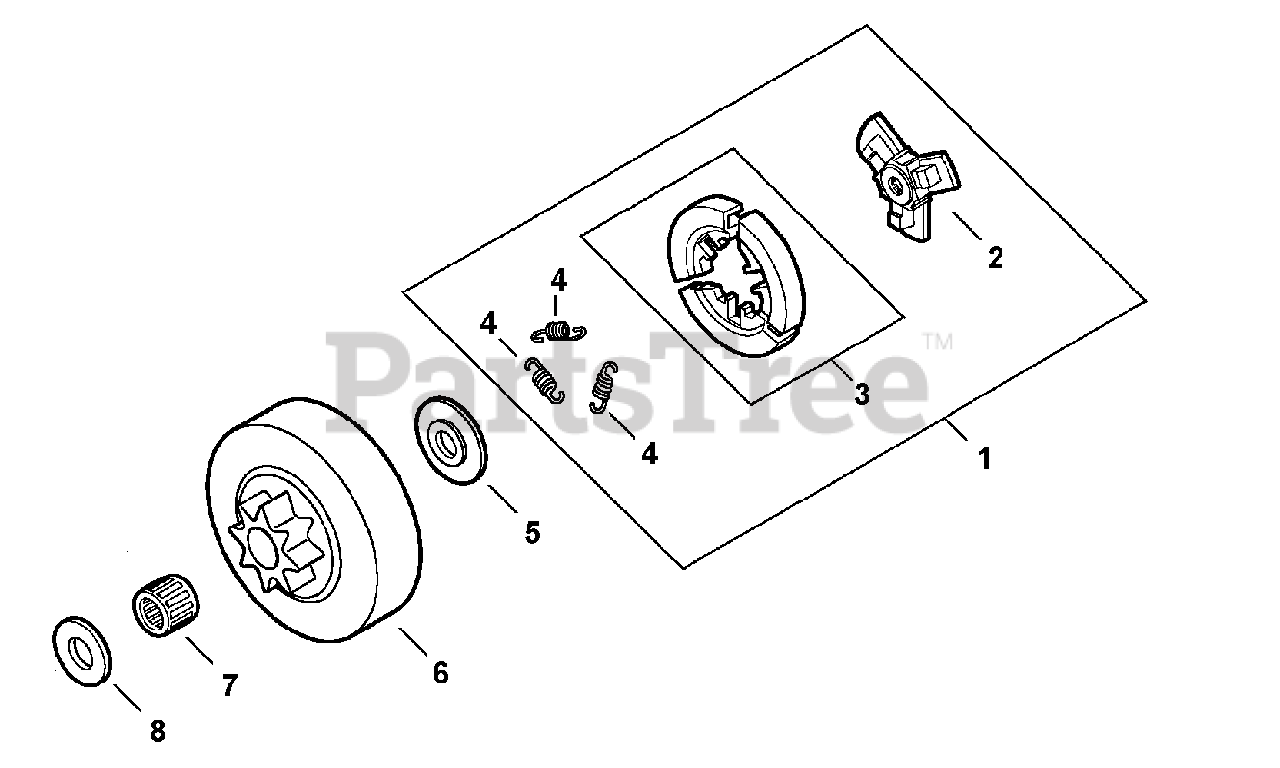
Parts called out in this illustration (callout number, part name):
1	CLUTCH ASSY
2	HUB, CLUTCH
3	SHOE SET, CLUTCH (3PCS)
4	SPRING, CLUTCH
5	PLATE, CLUTCH
6	DRUM, CLUTCH 3/8"
7	BEARING, NEEDLE
8	WASHER 10.2×24.5×1.2
